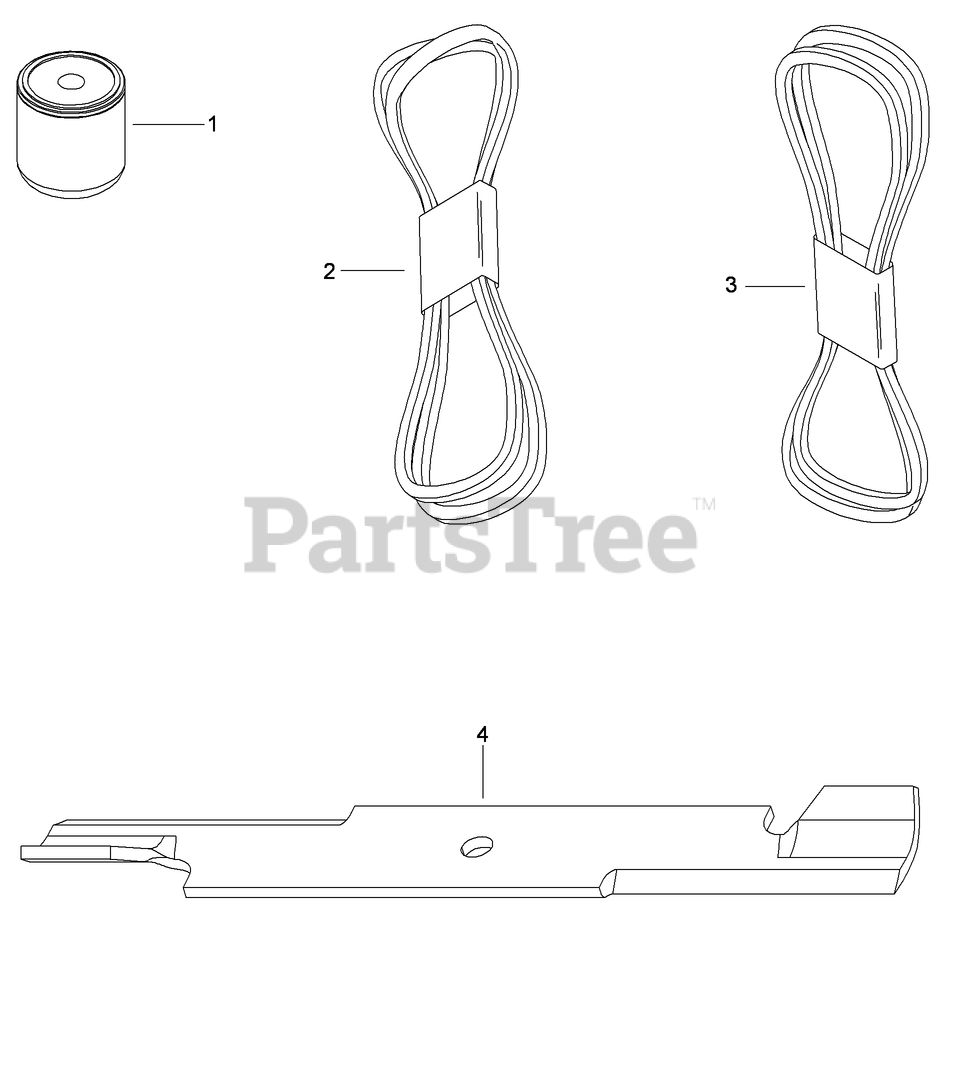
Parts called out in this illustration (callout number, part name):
1	FILTER-OIL, HYD
2	BELT-V
4	BLADE-18IN, HI FLOW
